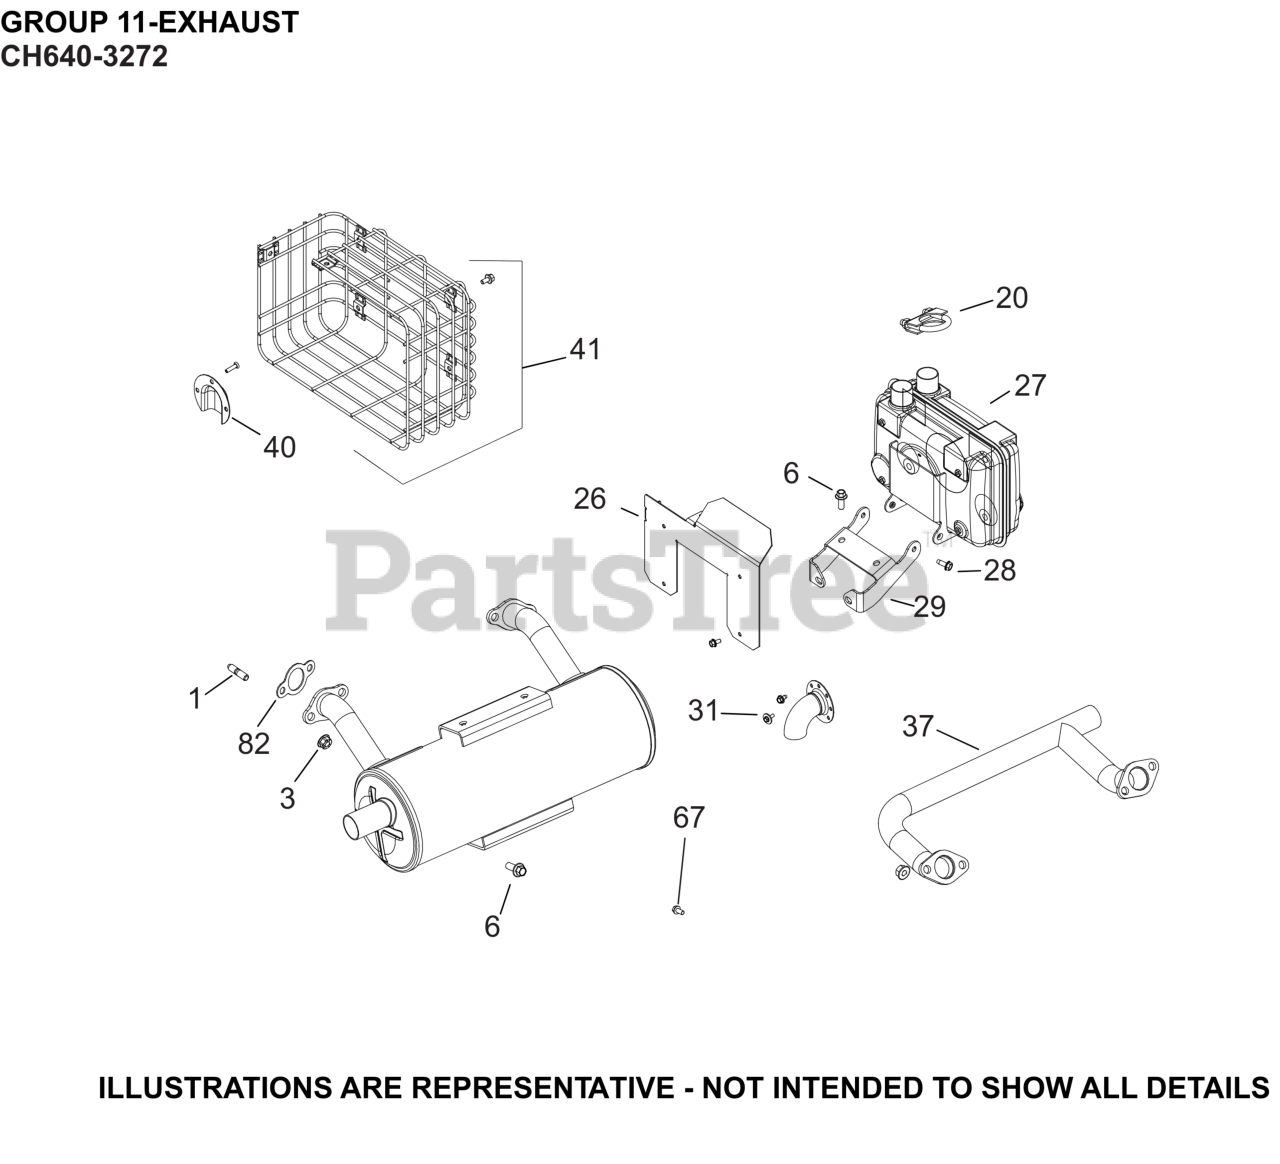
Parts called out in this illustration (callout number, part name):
1	STUD, METRIC EXHAUST
3	NUT, FLG M8X1.25
6	SCREW, FLG M8X1.25X20
20	CLAMP, MUFFLER
26	SHIELD, MUFFLER
28	SCREW, THREAD FORMING
29	BRACKET, MUFFLER
31	SCREW, SEMS DRILL #8-18X1/2"
37	MANIFOLD, EXHAUST
40	DEFLECTOR, EXHAUST
41	KIT, WIRE GUARD
67	SCREW, SERRATED
82	GASKET, EXHAUST MANIFOLD
